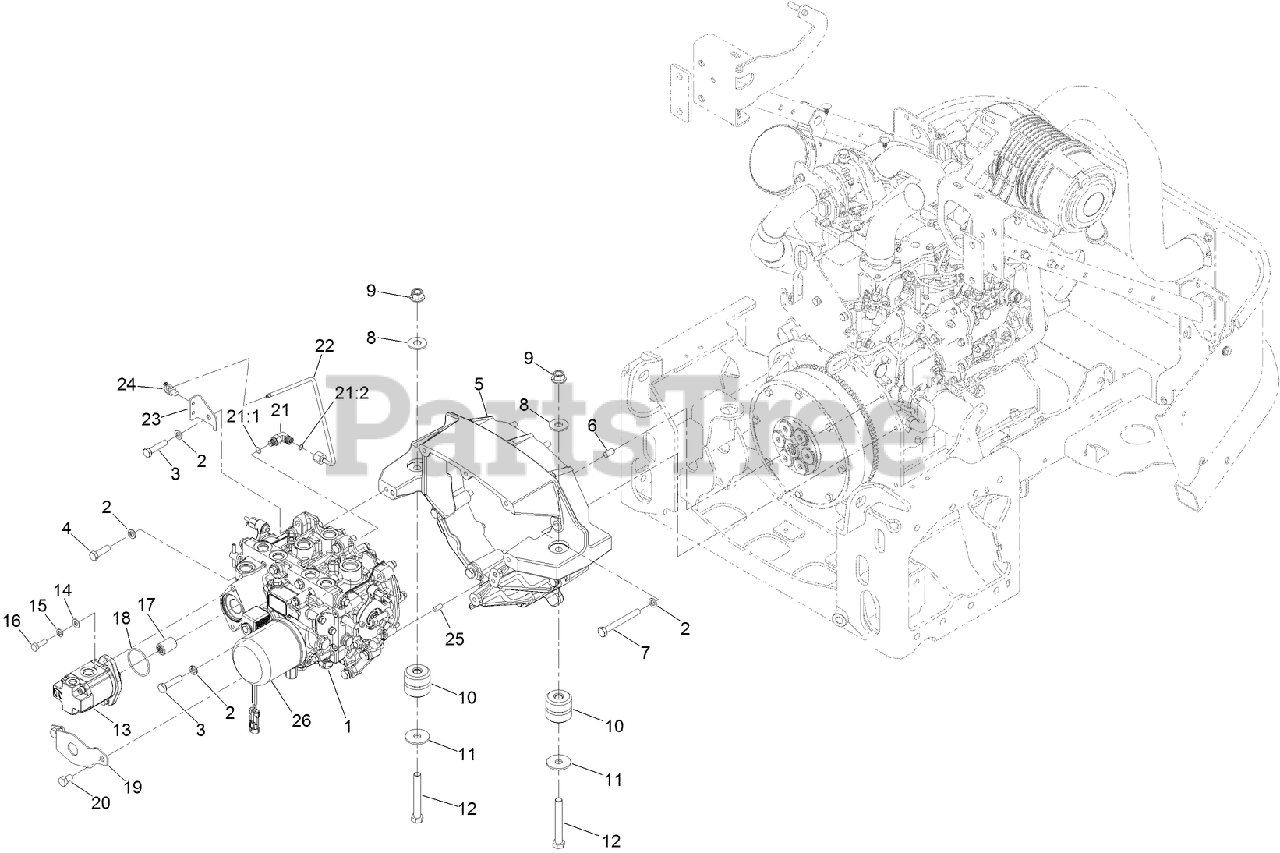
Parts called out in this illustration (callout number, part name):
1	TRANSMISSON ASM
2	WASHER-LOCK
3	SCREW-HH
4	SCREW-HH
5	HOUSING-FLYWHEEL
6	PIN-DOWEL
7	SCREW-HH
8	WASHER-FLAT
9	NUT-LOCK
10	MOUNT-ISOLATOR
11	WASHER-THRUST
12	SCREW-HH
13	HYD GEAR PUMP ASM
14	WASHER-PLAIN
15	SCREW-HH
16	SCREW-HH
17	COUPLER-SPLINE
18	O-RING
19	SHIELD-SEAL
20	SCREW-HH
21	FITTING-ELBOW, 90 DEG
21:1	O-RING
21:2	O-RING
22	TUBE ASM
23	SUPPORT-TUBE
24	CLIP-TIE
25	PIN-DOWEL
26	FILTER-OIL, HYD
